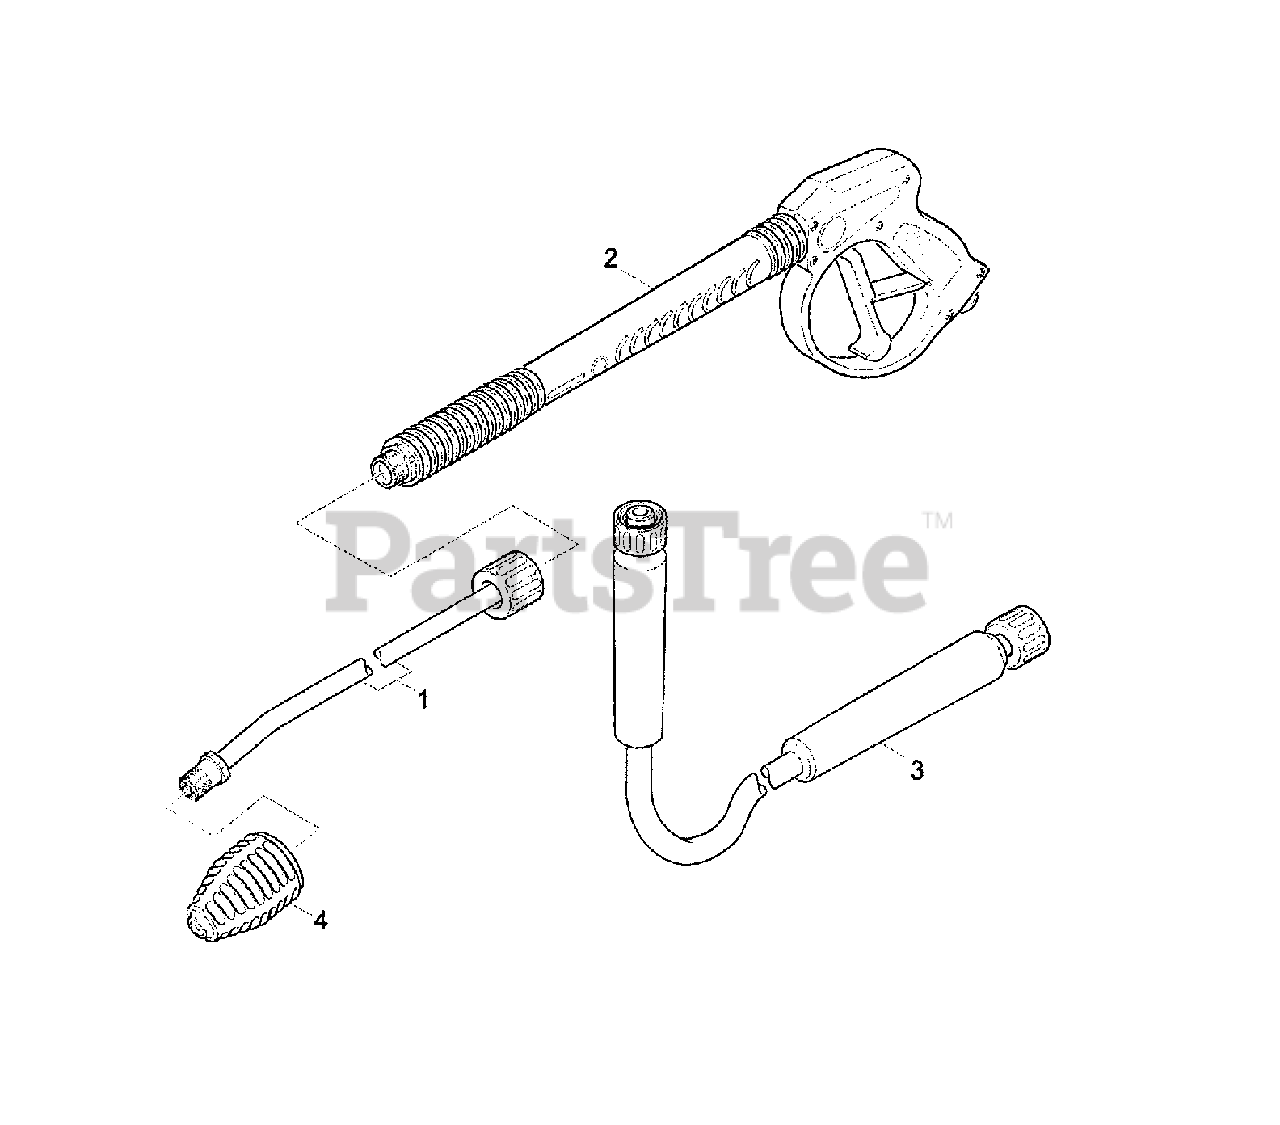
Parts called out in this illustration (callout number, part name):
2	Trigger Gun
3	High Pressure Hose
4	Rotary Nozzle
